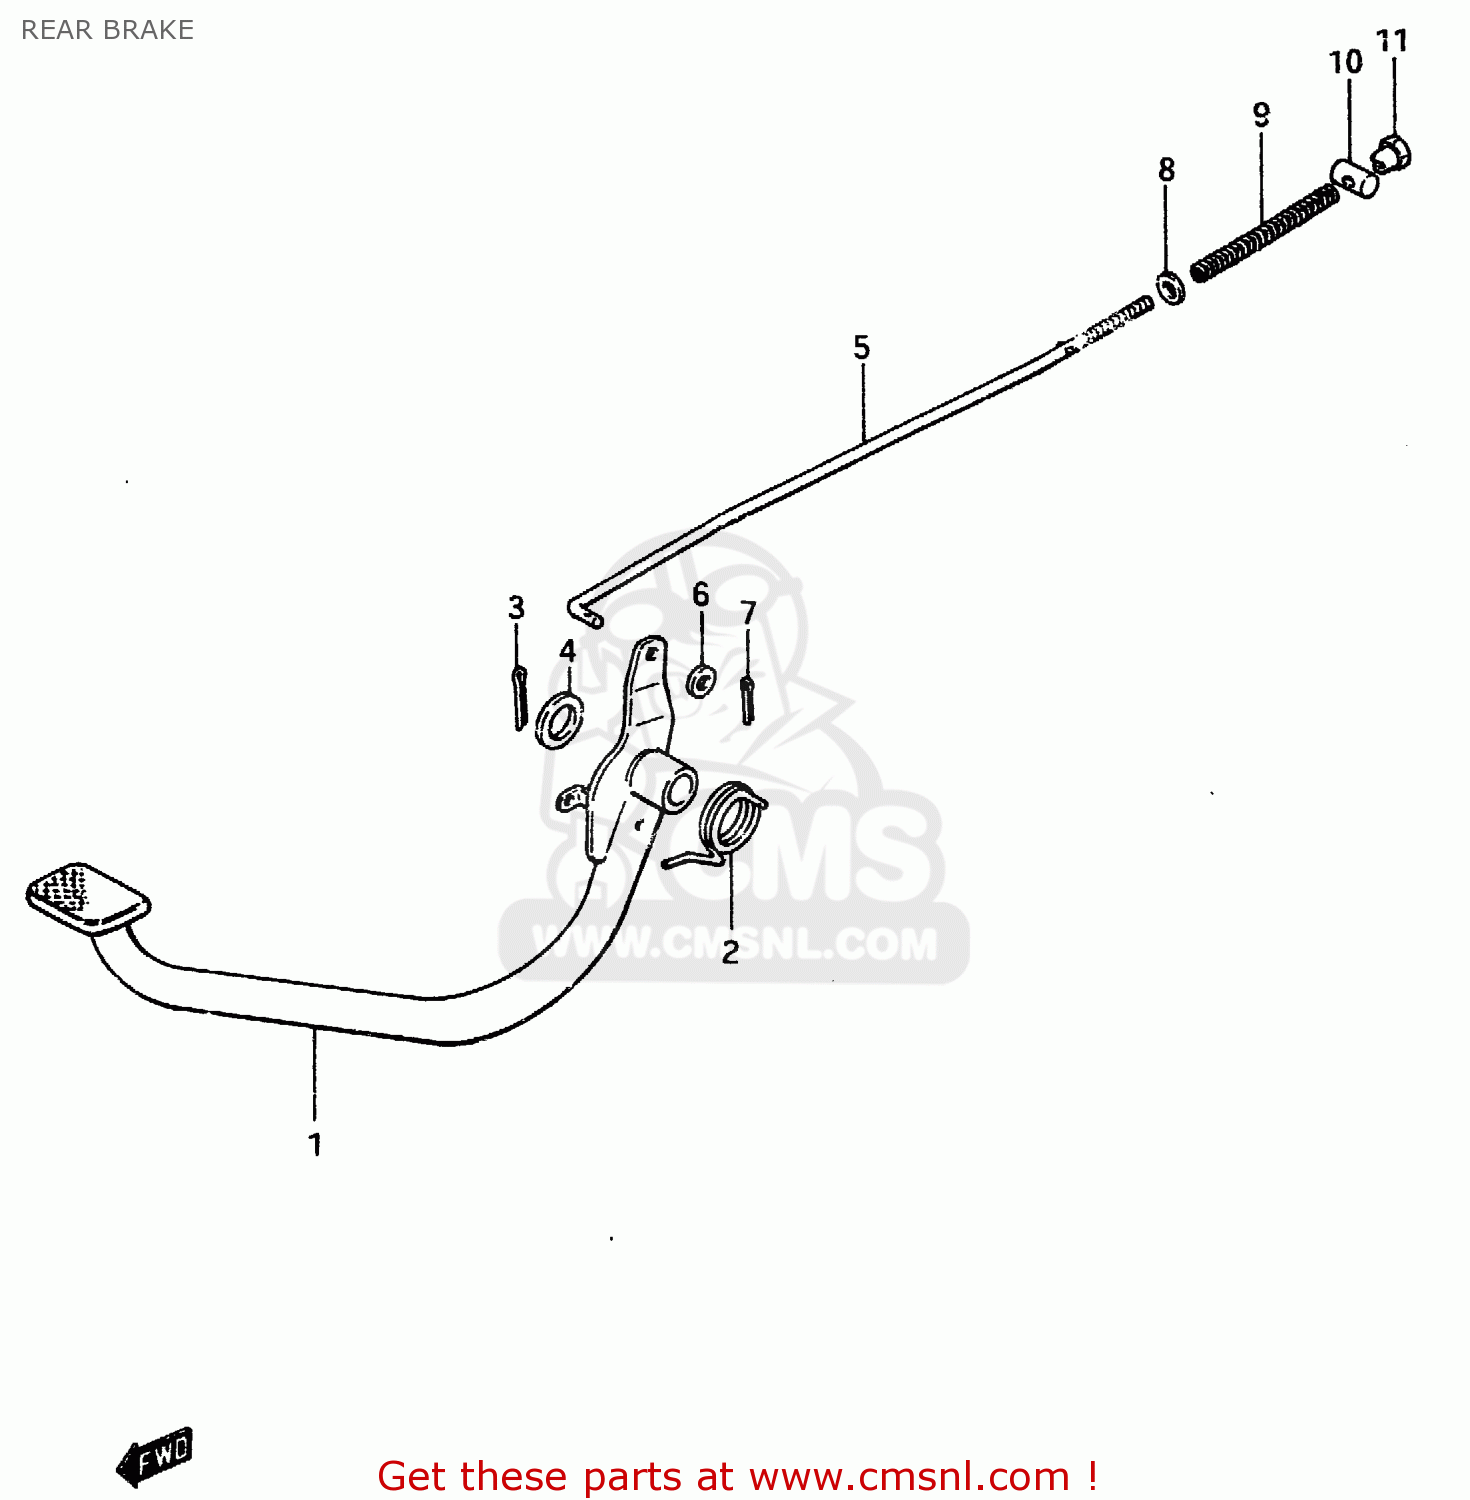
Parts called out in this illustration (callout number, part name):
1	PEDAL, BRAKE
2	SPRING
3	COTTER PIN
4	WASHER(15.5X26X2.3)
5	ROD ASSY,RR BRAKE
6	WASHER
7	PIN 20X20
8	WASHER
9	SPRING
10	PIN(11X18)
11	NUT
